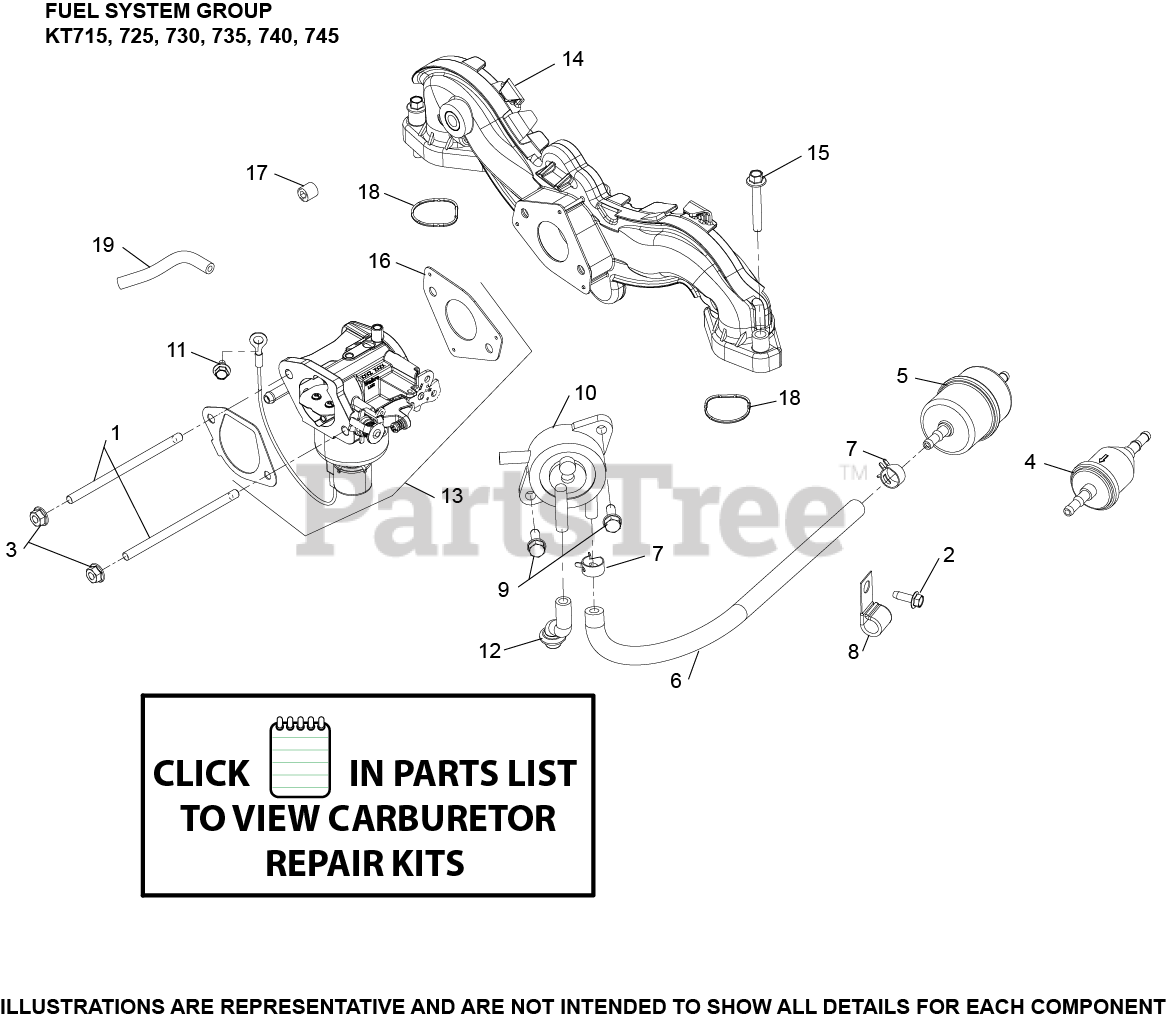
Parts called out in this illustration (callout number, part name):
2	SCREW, THREAD FORMING
3	NUT, FLG M6X1.0
4	FILTER,FUEL 51 MICRON (FUEL PUMP)
6	HOSE,LW PERM.FUEL 24.00"-USE 25 111 81-S
7	CLAMP SPRING HOSE
8	CLIP, CABLE
9	SCREW, TAP M6X1.7X18
10	PUMP, FUEL
11	SCREW, THREAD FORMING
12	HOSE, PULSE PUMP
13	KIT, CARBURETOR-USE 32 853 50-S
14	KIT, INTAKE MANIFOLD USE 24 164 266-S
15	SCREW, FLG M6X1.0X40
16	GASKET, CARBURETOR
17	PLUG, CTSK PIPE 1/8"
18	O-RING, INTAKE PORT
